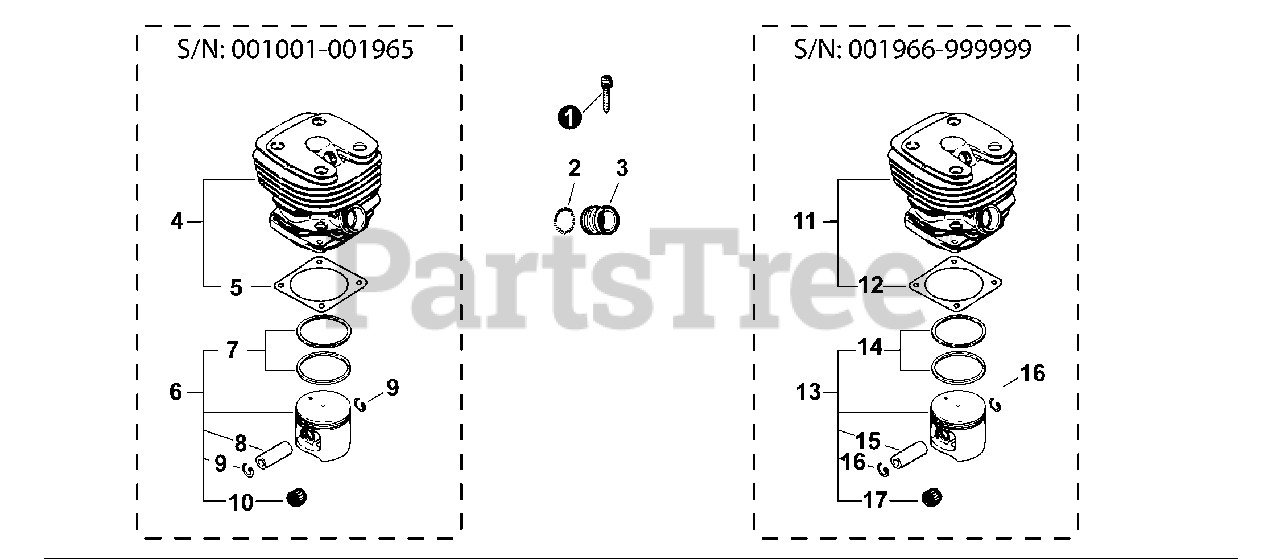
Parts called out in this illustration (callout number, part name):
1	BOLT 6×25
3	ADAPTOR, INTAKE
4	CYLINDER ASY
5	GASKET, CYLINDER BASE
6	PISTON KIT
7	RING, PISTON
8	PIN, PISTON
9	CIRCLIP, PISTON PIN
10	BEARING, NEEDLE
11	CYLINDER ASY
12	GASKET, CYLINDER
13	PISTON KIT
14	RING, PISTON
15	PIN, PISTON
16	CIRCLIP, PISTON PIN
17	BEARING, NEEDLE
